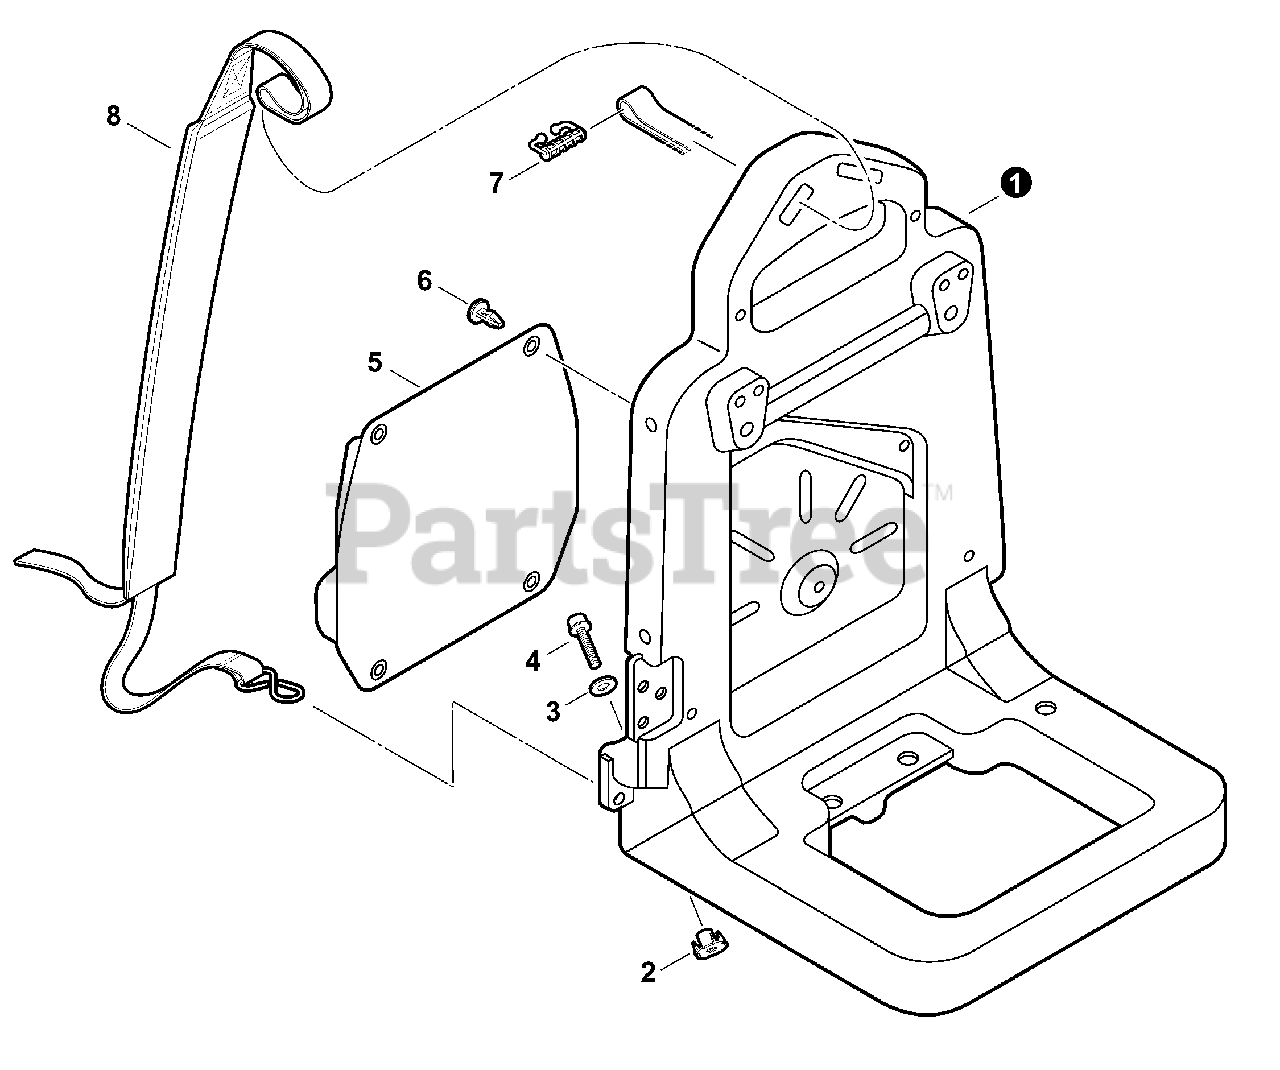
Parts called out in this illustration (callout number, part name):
1	FRAME, BACKPACK
3	WASHER 6.6×20×1.6
4	BOLT 6×25
5	CUSHION, BACKPACK
7	CLIP, HARNESS
8	HARNESS ASSY, BACKPACK
